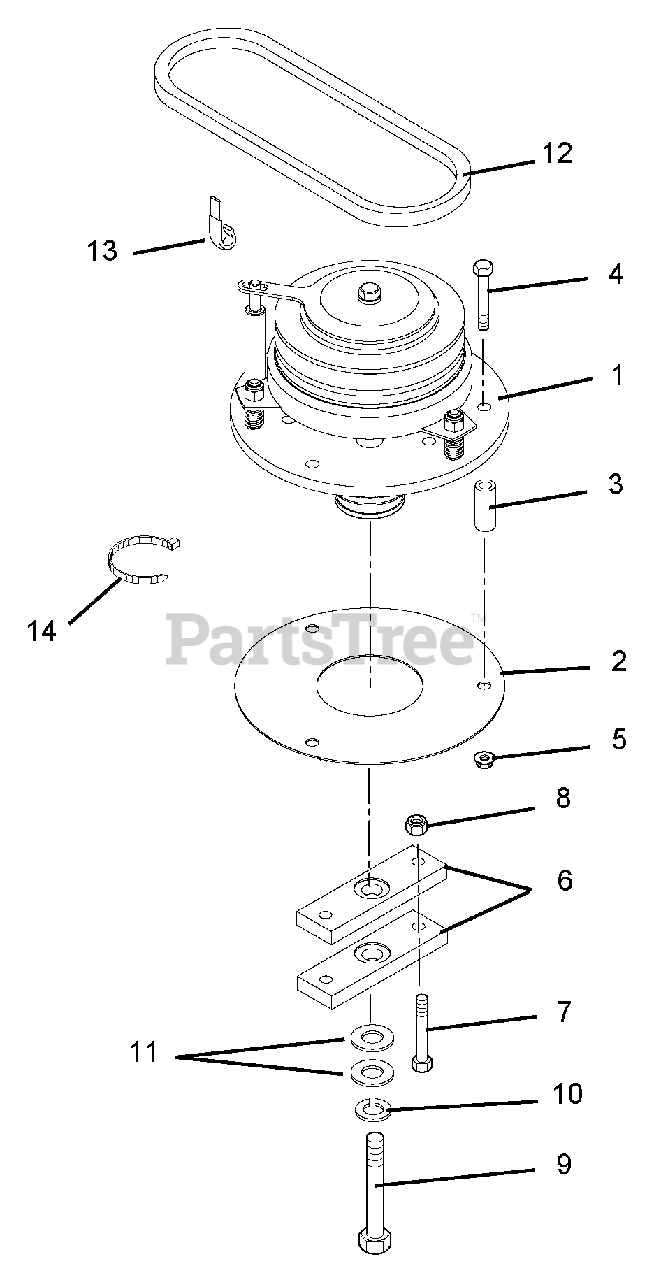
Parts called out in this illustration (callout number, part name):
1	Clutch/Spindle Assembly
2	Clutch Shield
4	3/8" x 2-3/4" Hex Bolt
5	Top Lock Flange Nut
6	Mower Blade Spacer
7	3/8" x 2" Hex Bolt
8	Nylon Locknut
9	5/8" x 2-1/2" Hex Bolt
10	Lock Washer
11	Flat Washer
12	PTO Belt Kit 52711800
14	Cable Tie
